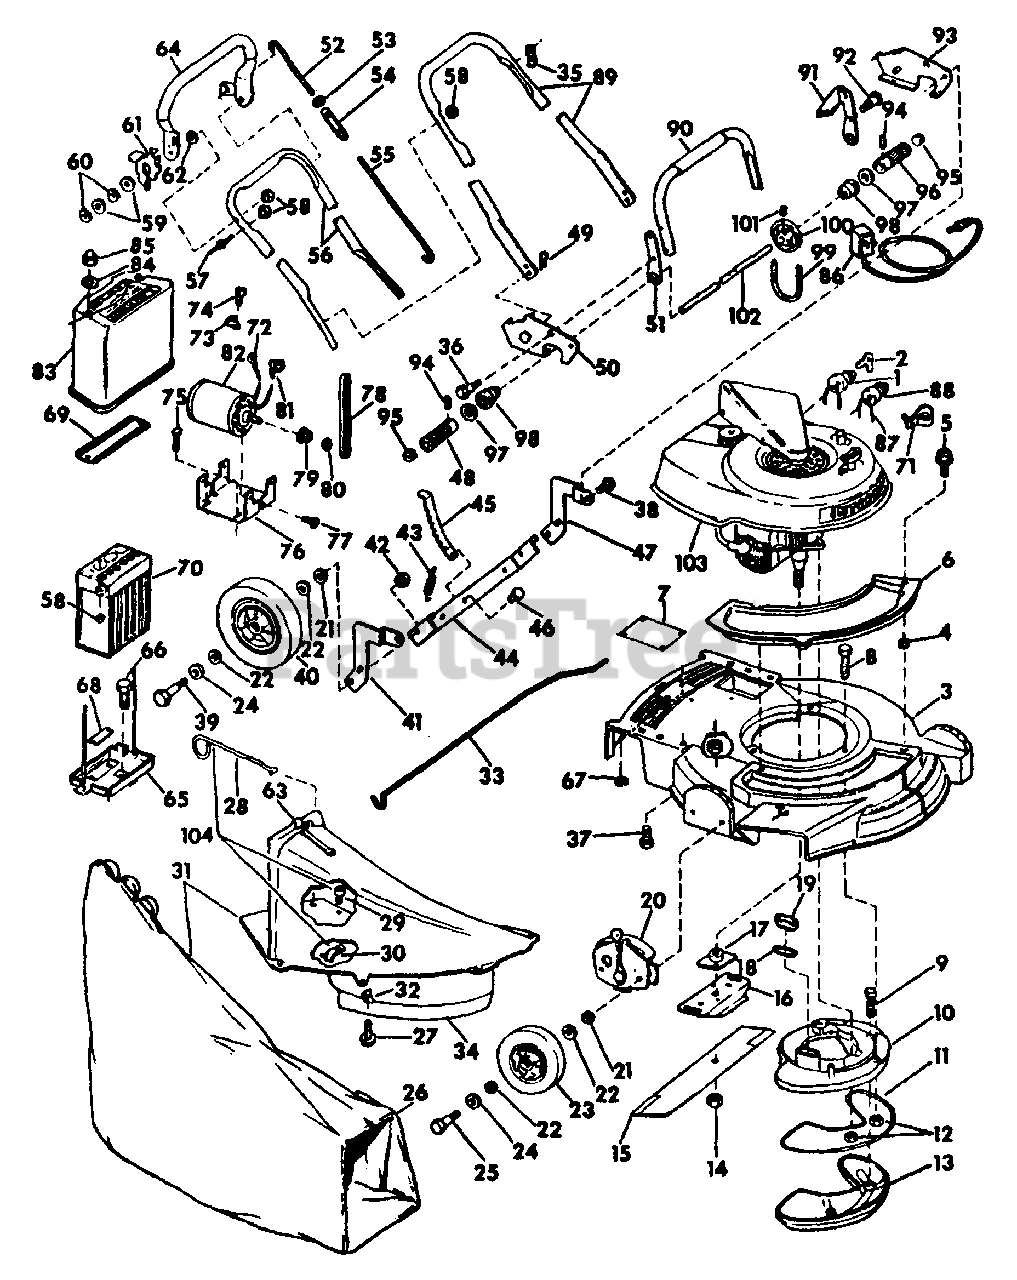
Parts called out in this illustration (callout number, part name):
3	HOUSING ASSY, 21 IN
4	NUT, GROMMET
5	SCREW, HEX-HD
6	COVER, CHUTE OPENING
7	COVER, POCKET
8	SCREW, MUFFLER PLATE TO HSG
9	SCREW, MUFFLER TO MUFFLER PLATE
10	PLATE W/SCREW, MUFFLER
11	GASKET, MUFFLER
15	BLADE, 21 IN.
16	STIFFENER, BLADE
17	COLLAR & PLATE
18	GASKET, EXHAUST
19	SLEEVE, EXHAUST GASKET
20	ADJUSTMENT, HEIGHT
22	WASHER, FELT
23	WHEEL & TIRE, 6 IN.
24	WASHER, WHEEL BOLT HD
25	BOLT, WHEEL FRT SHOULDER
28	GUARD, WHEEL
31	CHUTE ASSY
33	ROD, GRASS BAR
34	SKIRT ASSY, CHUTE
36	BOLT, SHOULDER
37	SCREW, HANDLE BRACKET
38	BOLT, SHOULDER
39	BOLT, REAR WHEEL
40	WHEEL AND TIRE, 8 IN.
41	BRACKET, WHEEL RIGHT REAR
42	NUT, REAR WHEEL BOLT
43	SPRING, HEIGHT ADJ
45	LEVER, HEIGHT ADJ REAR
47	BRACKET, WHEEL REAR LH
48	ROLLER, DRIVE RIGHT
50	BRACKET, HANDLE RIGHT
51	BRACKET, BRG CARRIER RH
52	ROD, CONTROL UPPER
55	ROD, CONTROL LOWER
56	HANDLE, CENTER
57	PIN, LOCKOUT
58	NUT, CENTERLOCK
60	WASHER, WAVE
61	CLIP, LOCKOUT
64	HANDLE & GRIP
65	BRACKET, BATTERY MTG
66	SCREW, BATTERY BRACKET
67	WASHER, BATTERY MTG BRACKET
68	STRAP, BATTERY MTG BRACKET
69	BRACKET, BATTERY HOLD-DOWN
71	RETAINER, WIRE LEAD TO TANK BRACKET
72	TERMINAL, MOTOR TO BATTERY
73	CLAMP, PIPE
75	SCREW, MOTOR & SWITCH MTG
76	BRACKET, MOTOR MTG
77	SCREW, THD CUTTING
78	BELT, STARTER MOTOR
81	TERMINAL, MOTOR TO SWITCH
82	MOTOR, ELECTRIC
83	COVER W/INSTRUCTION PRODUCT GRAPHIC, BATTERY
84	WASHER, BATTERY COVER
85	NUT, BATTERY COVER
86	CHARGER, TRICKLE
87	JACK LEAD & TERMINAL ASSY
89	HANDLE, LOWER
90	LINK, CONNECT
92	BOLT, SHOULDER
93	BRACKET, HANDLE LH
94	PIN, ROLLER TO SHAFT
95	PLUG, ROLLER GREASE
96	ROLLER, DRIVE LH
97	WASHER
98	SLEEVE & BEARING
99	V-BELT, DRIVEN
100	PULLEY W/SET SCREW, DRIVEN
103	ENGINE, IH
104	GUARD ASSY, WHEEL
